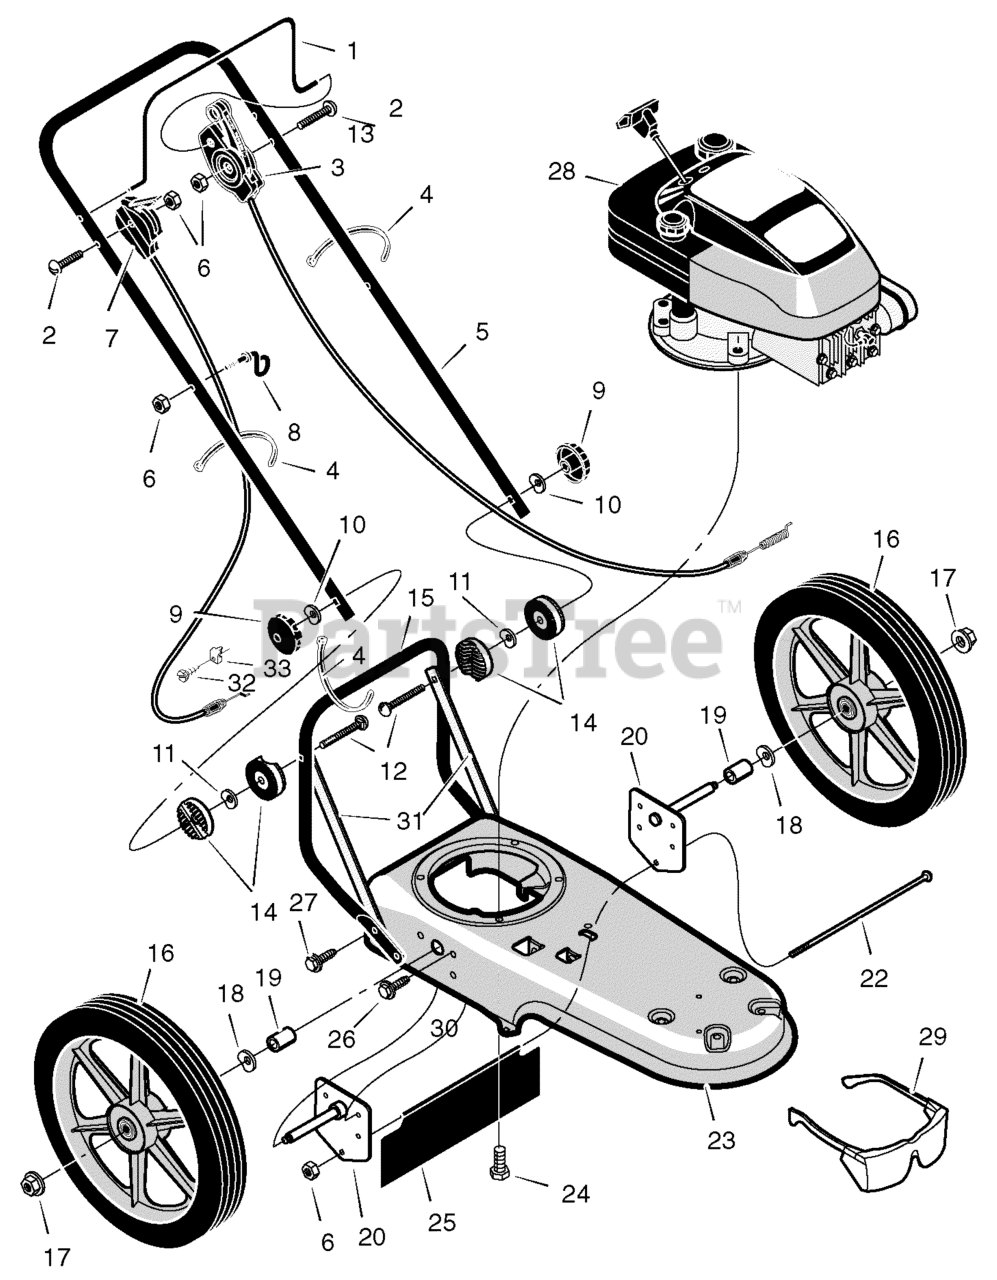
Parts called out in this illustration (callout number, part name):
1	Lever, Stop
3	Cable, Control Latching
4	Tie, Cable
5	Handlebar
7	Control, Throttle
8	Guide, Rope
9	Knob, Handlebar
10	Washer
11	Washer, Spring
13	Spacer
14	Pivot, Handlebar
15	Handlebar, Lower
16	Wheel & Tire
17	Nut, Axle
18	Washer, Spring
19	Spacer
20	Assembly, Axle & Bracket
22	Bolt, Carriage
24	Bolt
25	Shield, Trailing
26	Bolt
27	Screw
28	Engine
29	Glasses, Safety
30	Nut
31	Strap, Vibration
33	Clamp
